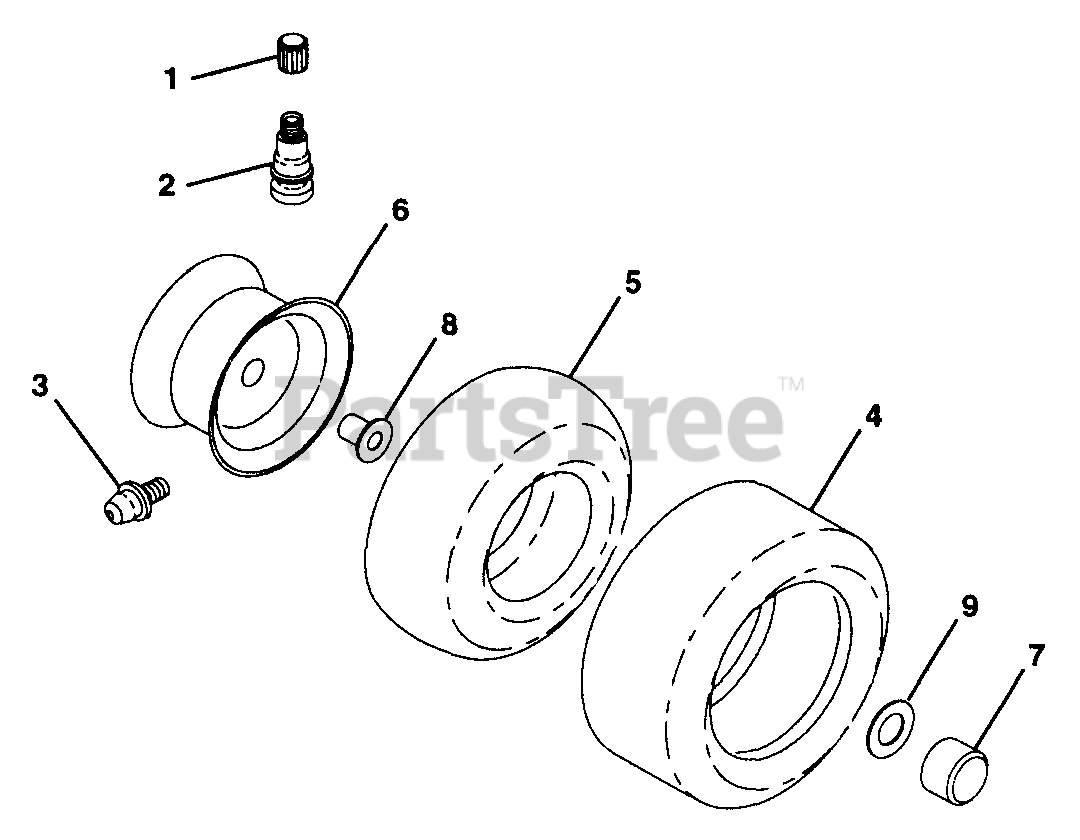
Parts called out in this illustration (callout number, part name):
1	Cap, Valve Stem
2	Stem, Valve
3	Fitting, Grease
4	Tire, Front
4	Tire, Rear
5	Tube, Front Tire
5	Tube, Rear Tire
6	Rim Front
7	Cap, Hub Axle
8	Bearing Flange
9	Washer 25/32 x 1-5/8 x 16 Gauge
